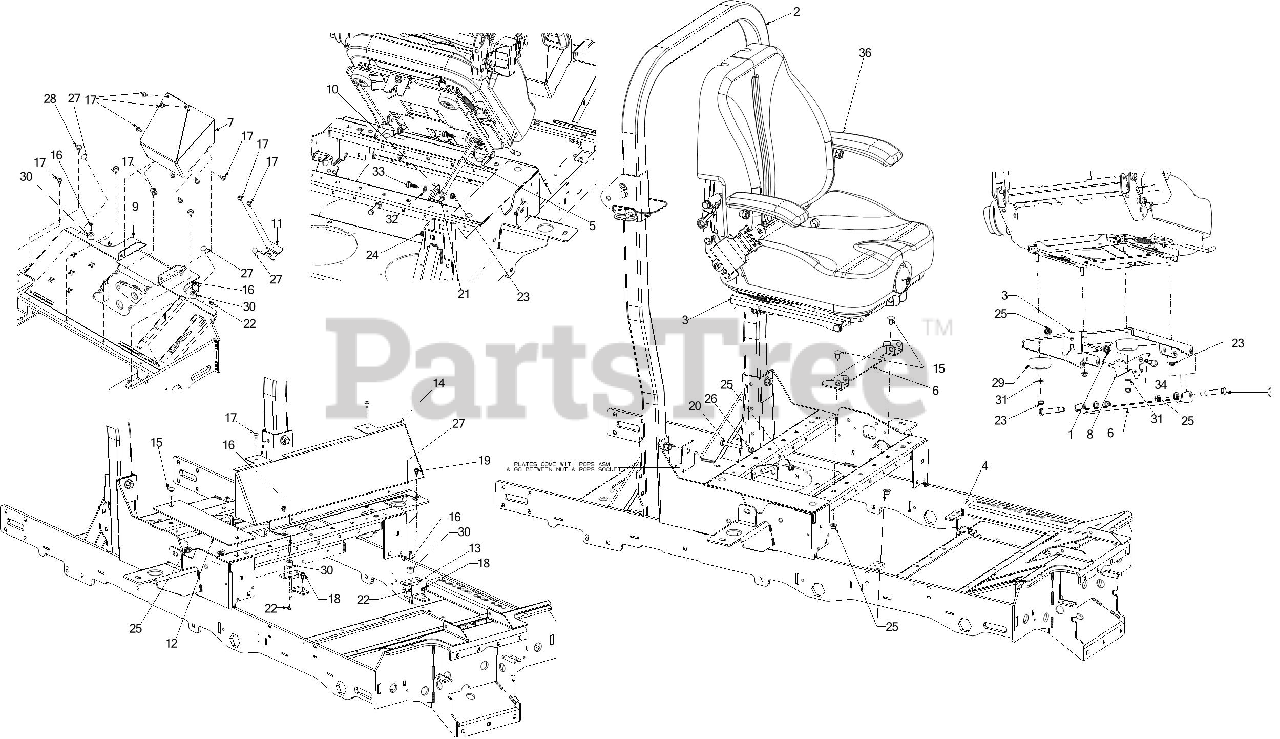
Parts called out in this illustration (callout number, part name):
1	HANDLE SPRING (LH)
2	ROPS ASSEMBLY
3	SEAT MOUNT BRACKET
4	FLOOR TRAY PANEL
5	SEAT LOCKOUT BRACKET
6	SEAT BRACKET
8	SEAT LATCH LEVER
9	STEERING PANEL COVER
10	SEAT LOCKOUT MOUNT
11	STOP BRACKET
12	SEAT COVER PANEL (RH)
13	FLOOR MOUNT BRACKET
15	CARRIAGE BOLT 3/8-16 x .750 GR5
16	SCREW 10-24 x .750
17	SCREW 1/4-20 x .5
18	SCREW 1/4-20 X.500
19	SCREW 1/4-20 x .375
20	HEX SCREW-3/8-16X2.5 GR5
21	SCREW 1/4-20X.75 GR5
23	FLANGE LOCK NUT 5/16-18
24	FLANGE LOCK NUT
26	HEX NUT
27	RATCHET CLIP
28	BUMPER, .62 DIA x .3
29	RUBBER BUMPER
30	RUBBER BUMPER
31	FLAT WASHER
32	FLAT WASHER .469X.750X.054
33	SHOULDER SCREW .437
34	SHOULDER SCREW .50X.925
35	SHOULDER SCREW .50 x 2.23 3/8-16
36	SEAT (COMMERCIAL)
